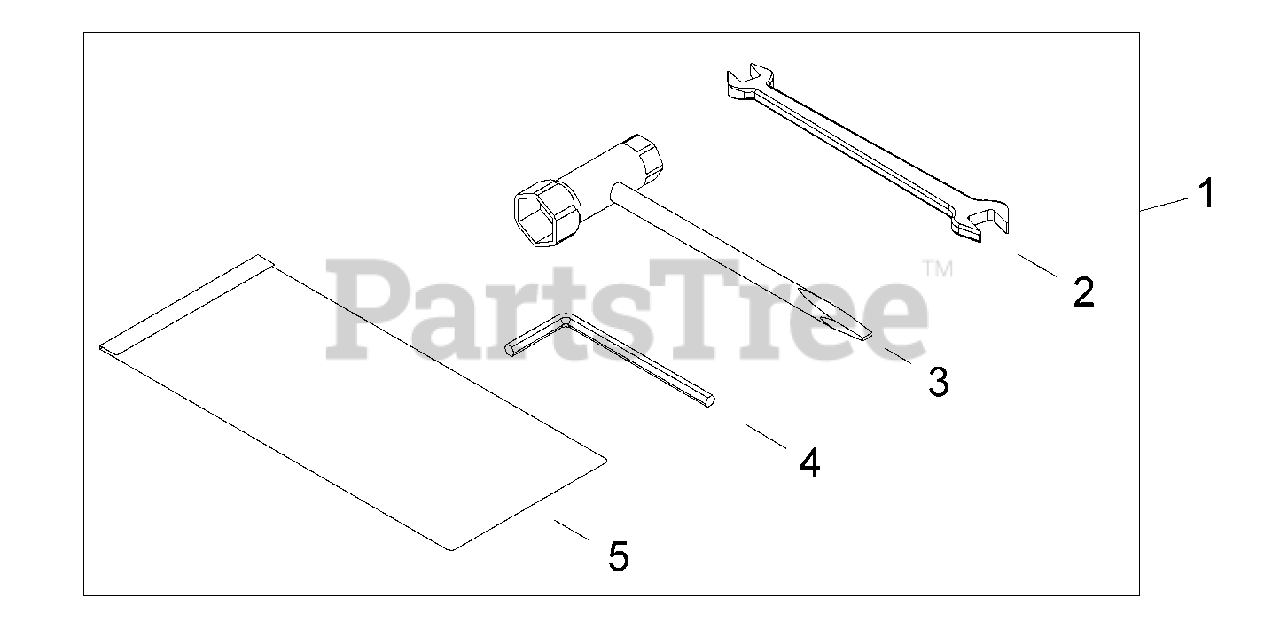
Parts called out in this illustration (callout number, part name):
1	TOOL KIT, SERVICE
2	SPANNER 8×10
3	T-WRENCH 16×13
4	WRENCH, ALLEN 4 MM
5	BAG, TOOL
